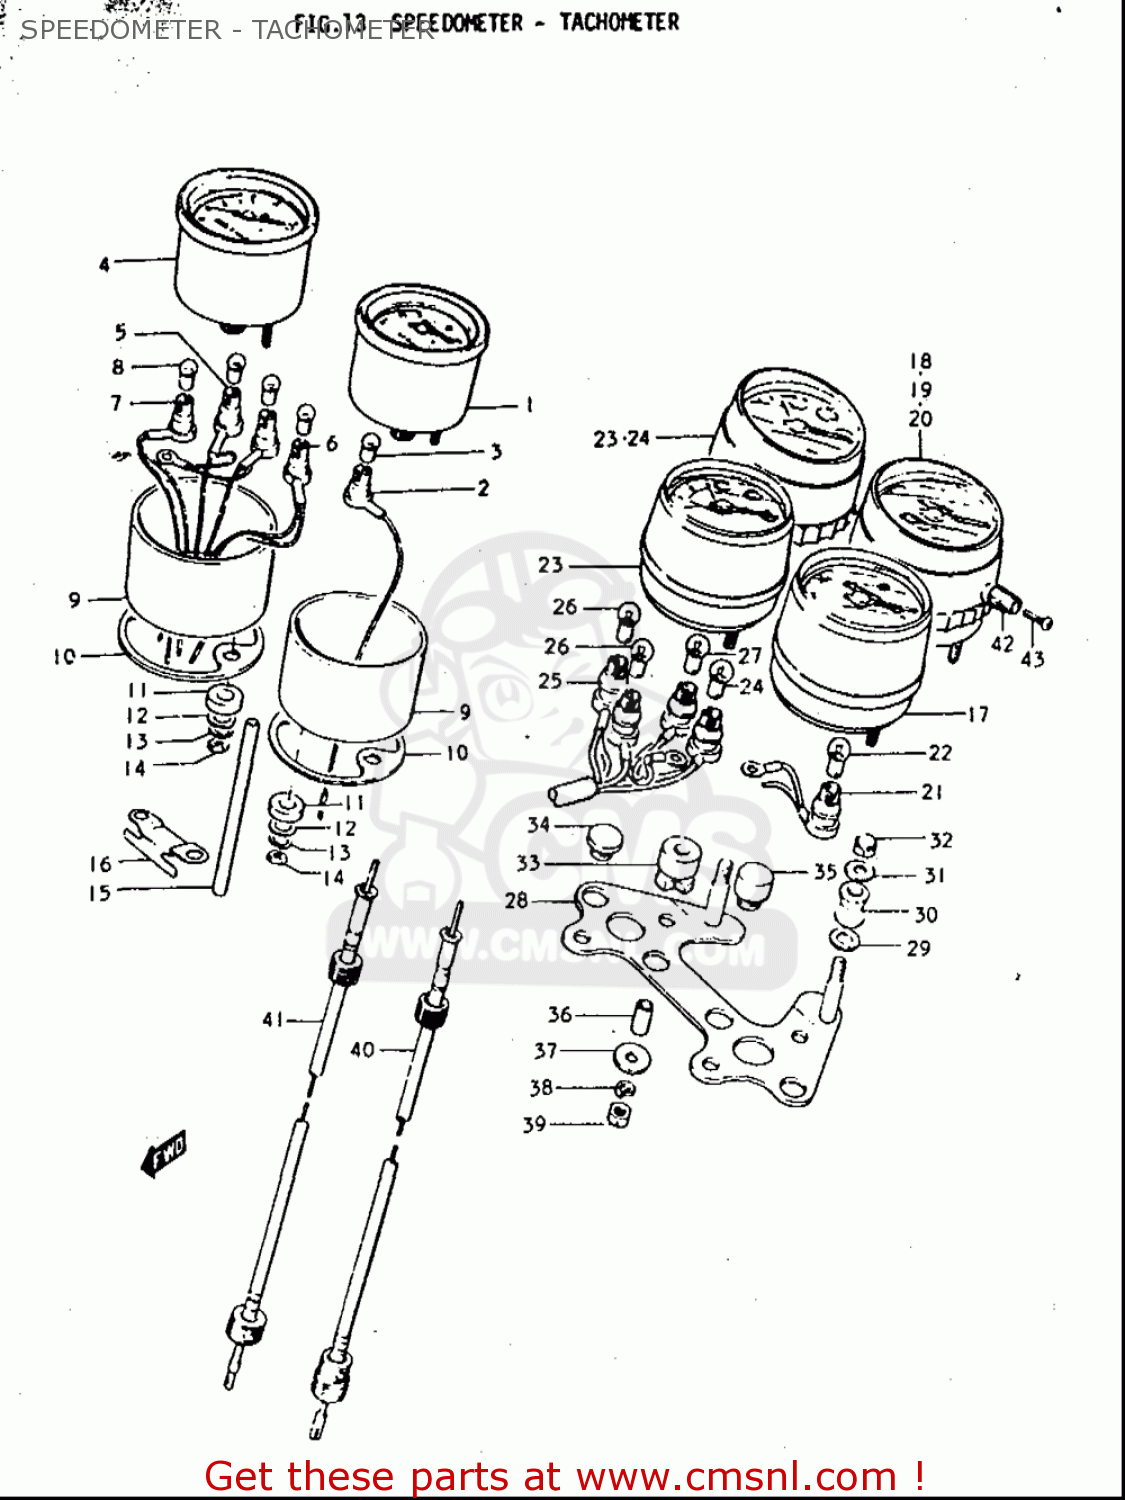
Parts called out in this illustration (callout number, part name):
3	BULB(12V3.4W,STANLEY,A72A)
8	BULB(12V3.4W,STANLEY,A72A)
11	CUSHION
12	WASHER (5.5X18X1.6)
13	WASHER,LOCK
14	NUT
22	BULB(12V3.4W,STANLEY,A72A)
26	BULB(12V3.4W,STANLEY,A72A)
27	BULB(12V1.7W,A71A)
29	WASHER(6.5X18X1.6)
30	CUSHION
31	WASHER
32	NUT
33	CUSHION,METER NO.1
37	WASHER(6.5X18X1.6)
38	WASHER,LOCK
39	NUT
40	CABLE ASSY,SPEEDOMETER
41	CABLE ASSY,TACHOMETER
43	SCREW(2X6)
